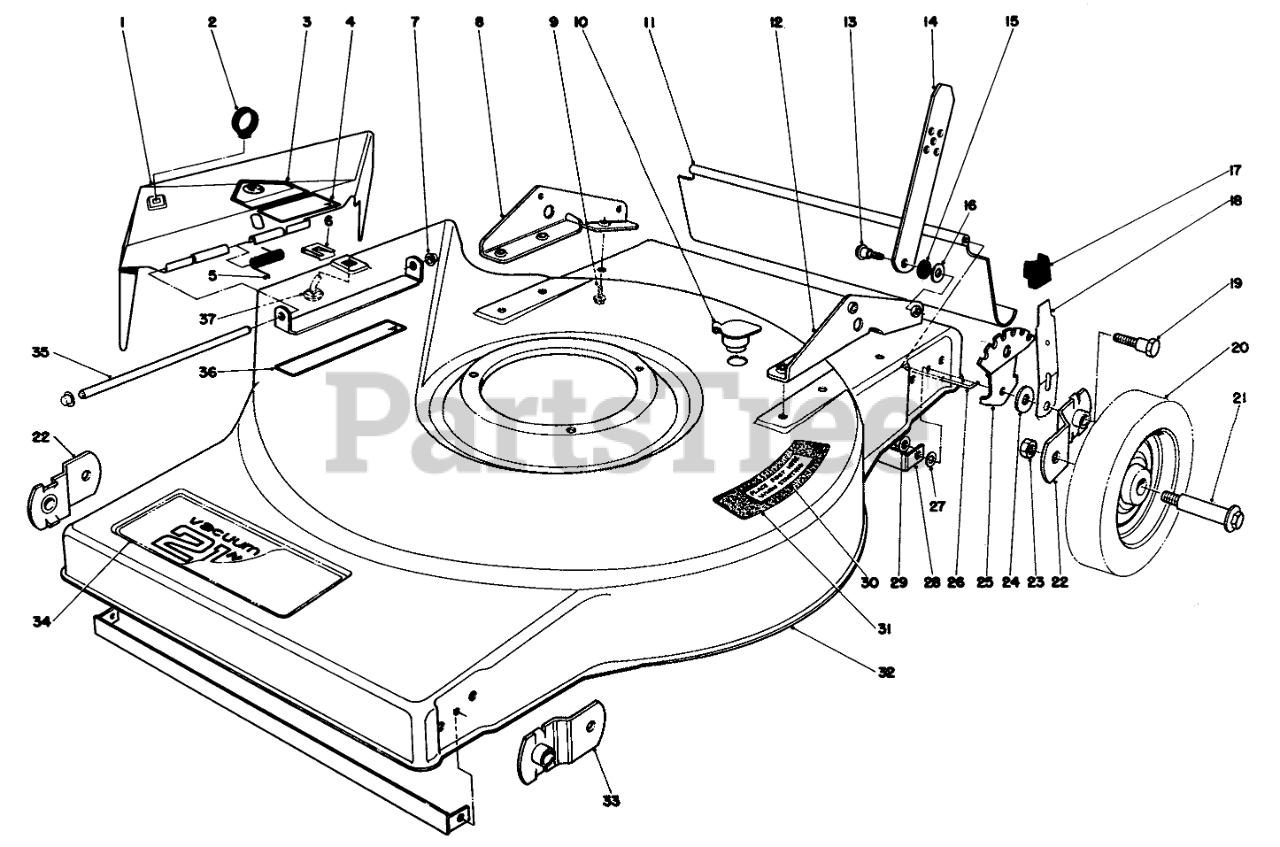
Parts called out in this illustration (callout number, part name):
1	DefIector
2	LIFT LOOP
3	DECAL-DANGER
4	DECAL DEFLECTOR
5	TORSION SPRING
6	BAG CHUTE CLIP PIN
7	PUSHNUT-CAP, WASHER
8	Bracket Handle R.H.
9	SCREW-HWHTF
10	WASHOUT PLUG
11	SAF SHIELD REAR
12	Bracket-L.H.
13	SCREW-SHOULDER
14	Handle Latch
15	SPACER
16	WASHER-PLAIN
17	KNOB-ARM
18	SPRING ARM ASM
19	PIVOT SCREW
20	Wheel Assembly
22	PIVOT ARM ASM A
23	Nut
24	PIVOT WASHER
25	Quadrant
26	SHIELD ROD
27	WASHER
28	DECK SUPPORT
30	Decal Step Pad
31	PAD STEP
32	Housing
33	PIVOT ARM ASM B
34	Decal-Deck
35	DEFLECTOR PIVOT ROD
36	DECAL CAUTION
37	BAG CHUTE PIN
